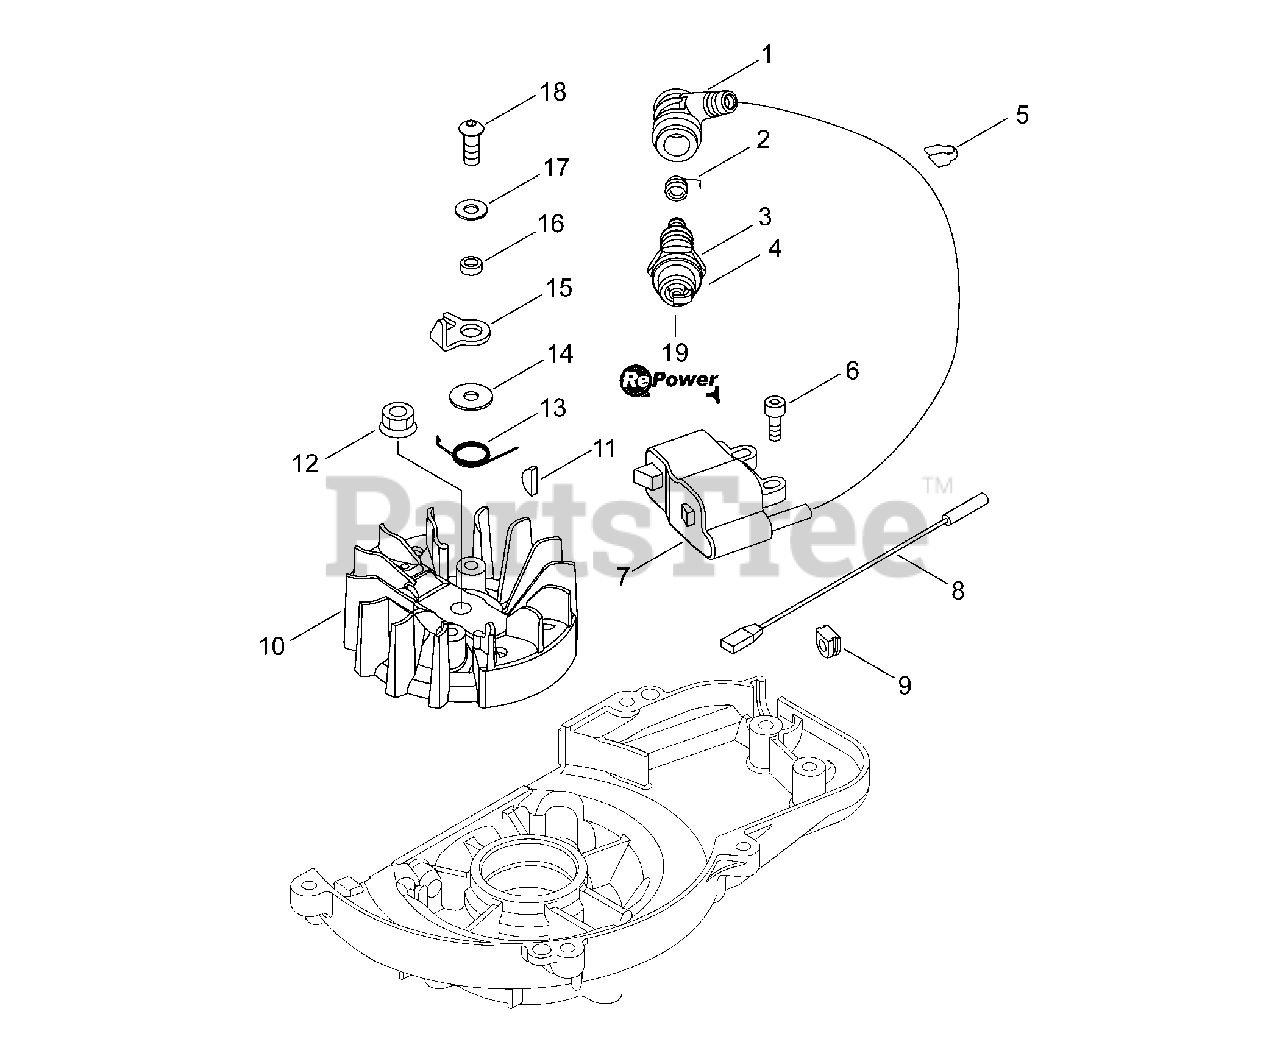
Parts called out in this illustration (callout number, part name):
1	CAP, SPARK PLUG
2	TERMINAL, SPARK PLUG
3	SPARK PLUG - BPM8Y
4	SPARK PLUG - BPMR8Y
5	LABEL, SPARK PLUG - BPM8Y
6	BOLT, TORX 4×16
7	COIL, IGNITION
8	LEAD L= 85 MM
9	GROMMET
10	FLYWHEEL
11	KEY, WOODRUFF
12	NUT, FLANGE M6
13	SPRING, TORSION
14	WASHER 5.5×16×0.8
17	WASHER 5.5×12×0.8
18	BOLT 5×14
19	TUNE-UP KIT - REPOWER
